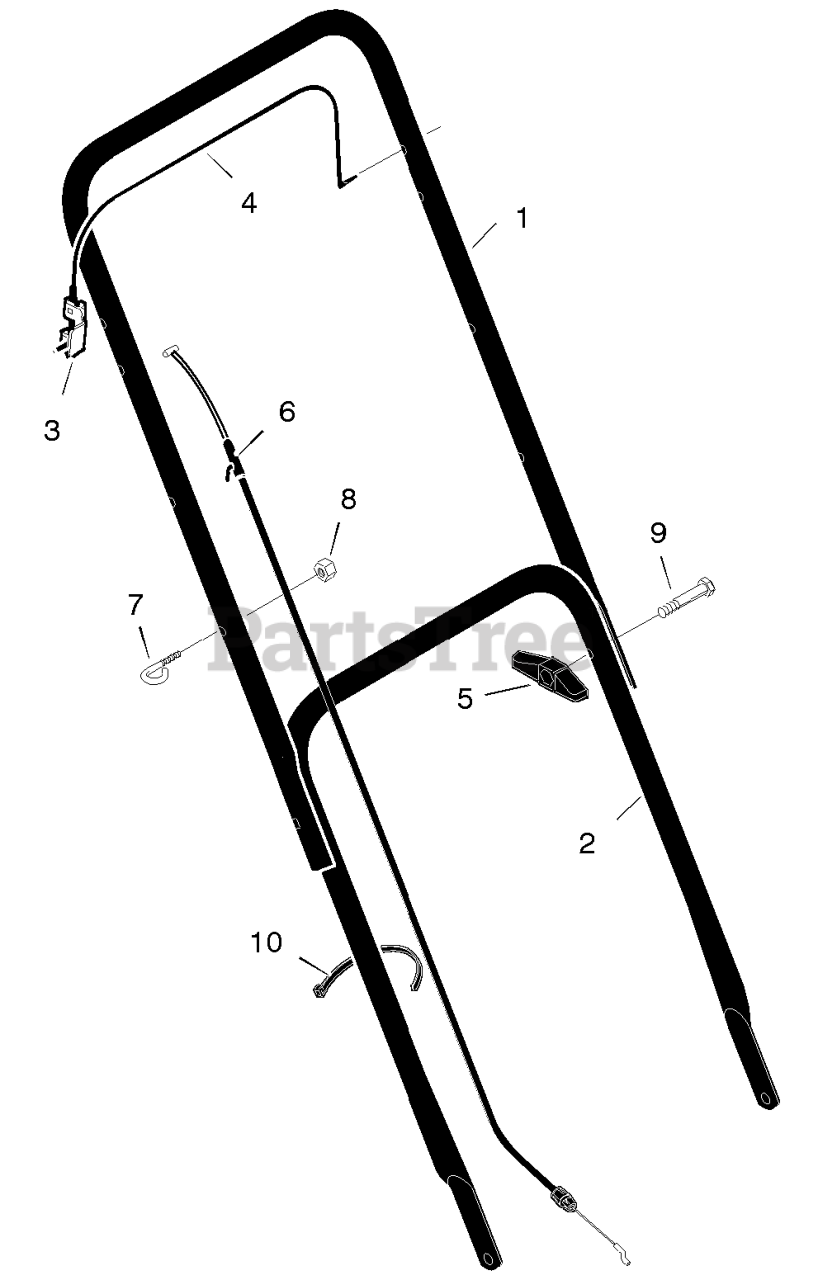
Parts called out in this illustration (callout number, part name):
1	Handle, Upper (Black)
2	Handle, Lower (Black)
3	Bracket, Stop Lever
4	Lever, Stop
5	Knob, Plastic
6	Engine Stop Cable
7	Guide, Rope
8	Locknut
10	Fastener, Cable
